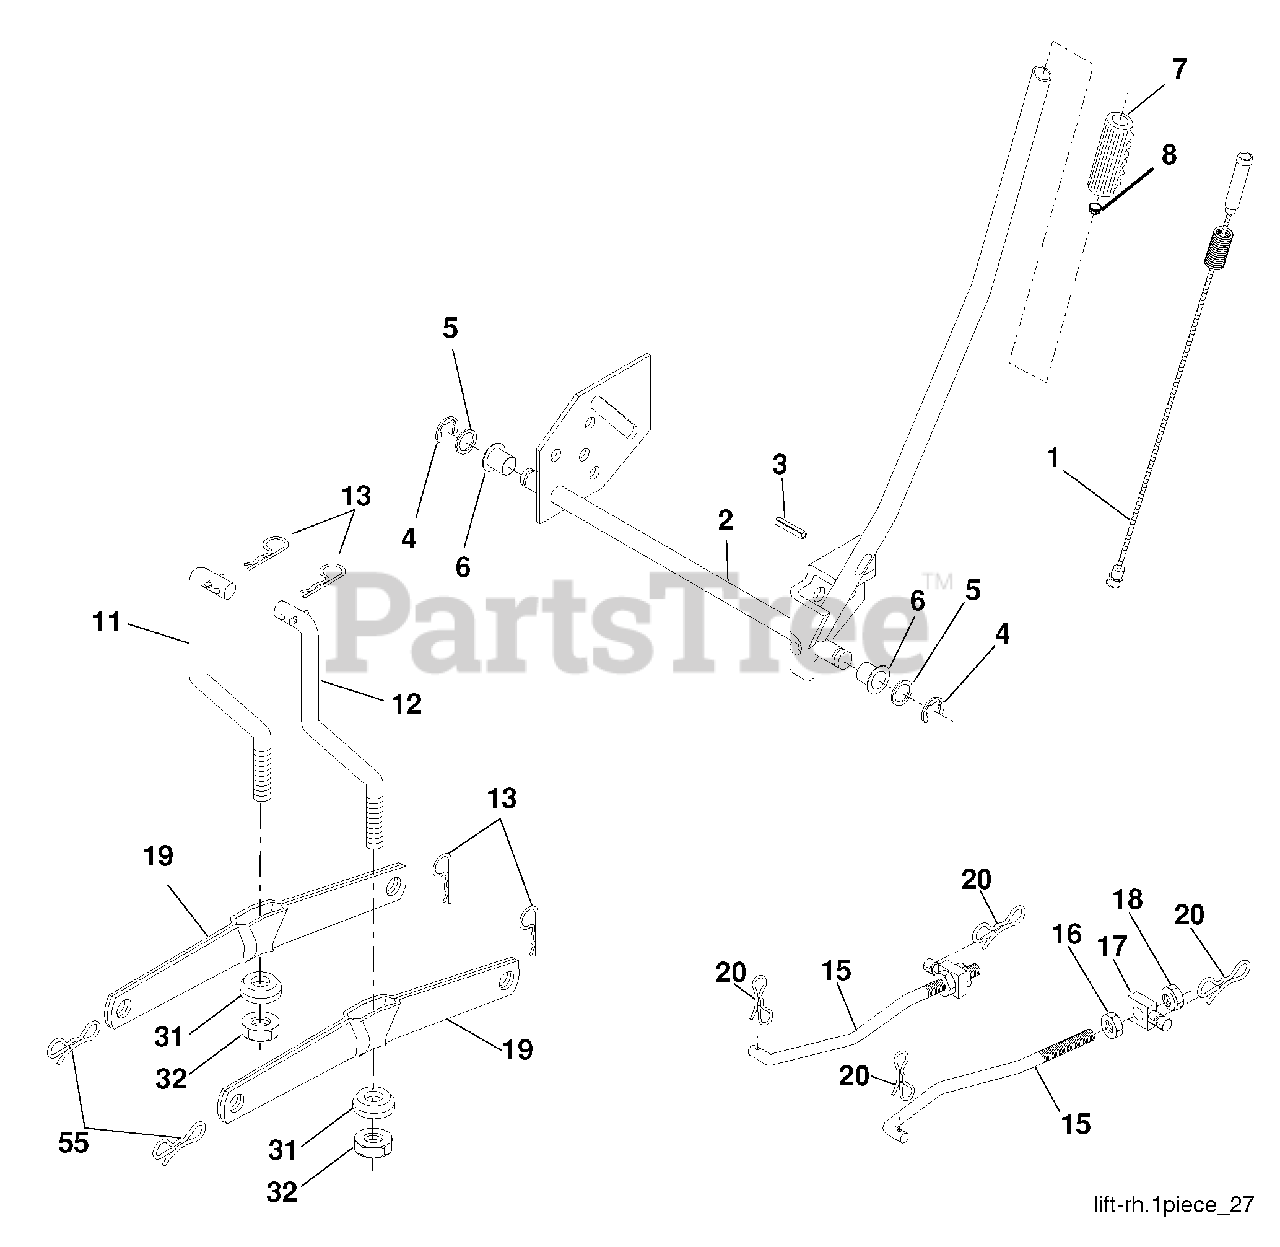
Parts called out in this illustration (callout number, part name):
1	Plunger Asm Lift Lever Blk
2	Shaft Asm Lift RH
3	Pin Groove 1 500 Zinc
4	E Ring #5133-62
5	Washer 21/32 x 1 x 21 Ga.
6	Bearing Nylon Blk 629 Id
7	Grip Handle Bicycle Matte Blk
8	Button Plunger Black
11	Link Lift LH Fixed Length
12	Link Lift RH Fixed Length
13	Retainer Spring
15	Link Front
16	Nut Jam Hex 1/2-13 unc
17	Trunnion
18	Nut Lock w/Wsh 1/2-13 unc
19	Arm Suspension Rear
20	Pin Cotter 7/16 Bow Tie Lock
31	Bearing Pvt Lift
32	Nut Crownlock 3/8-24
55	Pin Cotter 5/16 Bow Tie Lock
